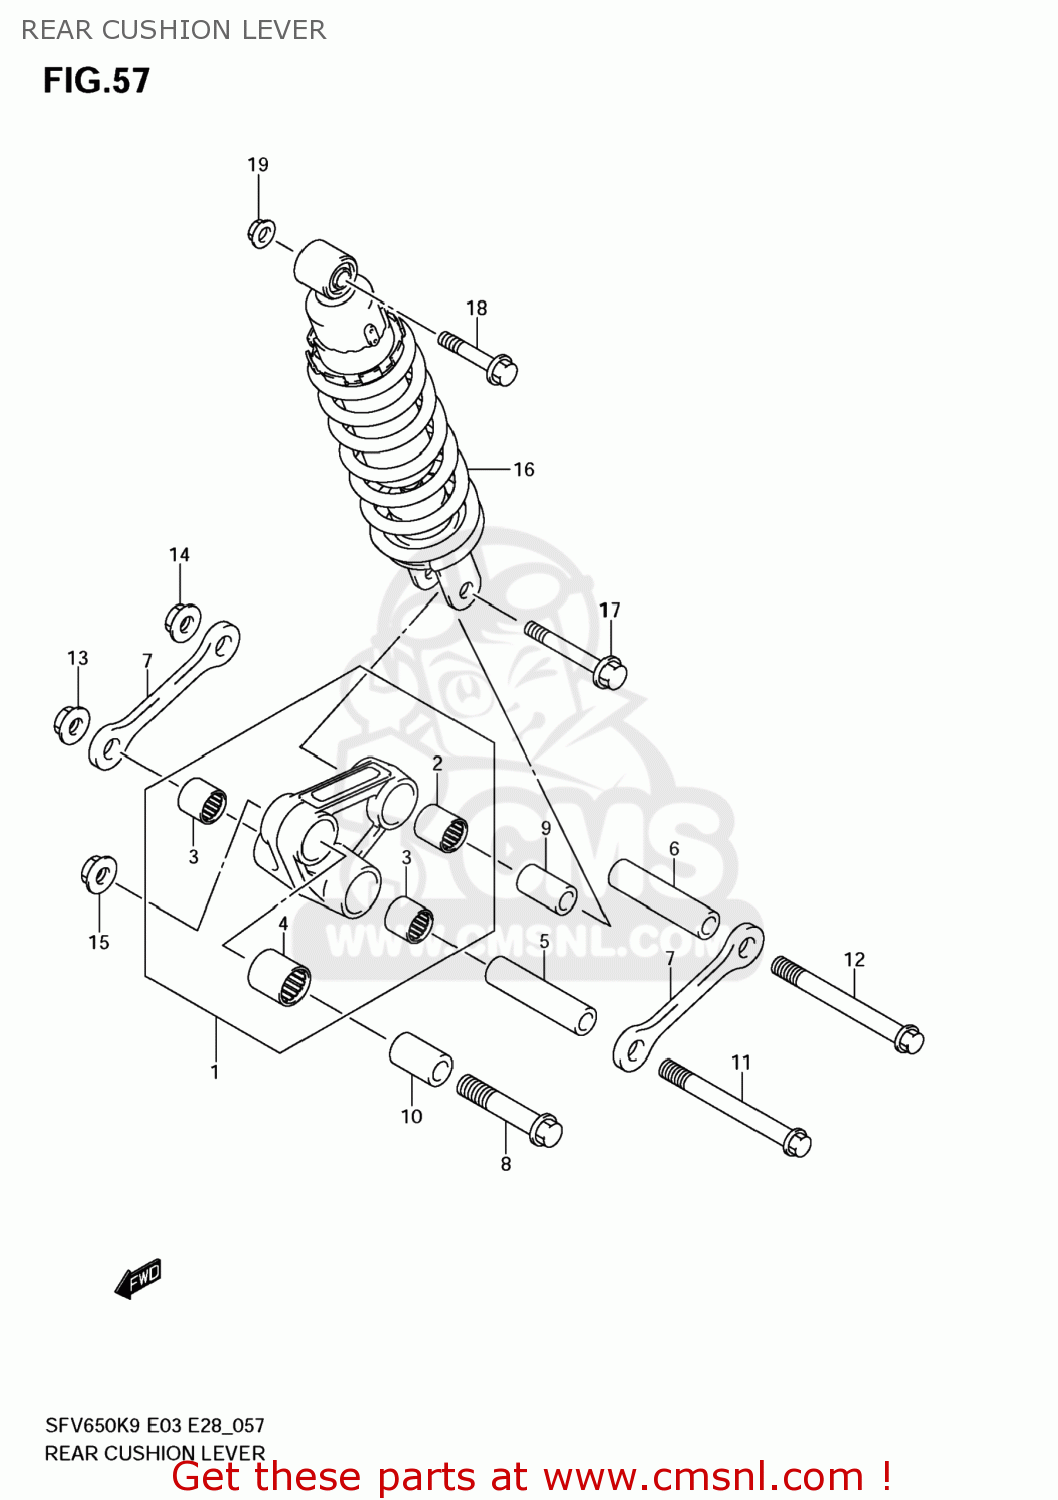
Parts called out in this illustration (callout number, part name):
1	LEVER SET,RR CUSHION
2	BEARING(17X24X26)
3	BEARING(17X24X25)
4	BEARING(20X27X30)
5	SPACER,RR CUSHION LEVER CTR
6	SPACER,RR CUSHION LEVER CTR
7	ROD,RR CUSHION LEVER
8	BOLT,CUSHION LEVER FR
9	SPACER,RR CUSHION LEVER
10	SPACER,RR CUSHION LEVER FR
11	BOLT(12X96)
12	BOLT(12X96)
13	NUT
14	NUT
15	NUT
16	ABSORBER ASSY,RR SHOCK
17	BOLT(10X48)
18	BOLT(10X52)
19	NUT
